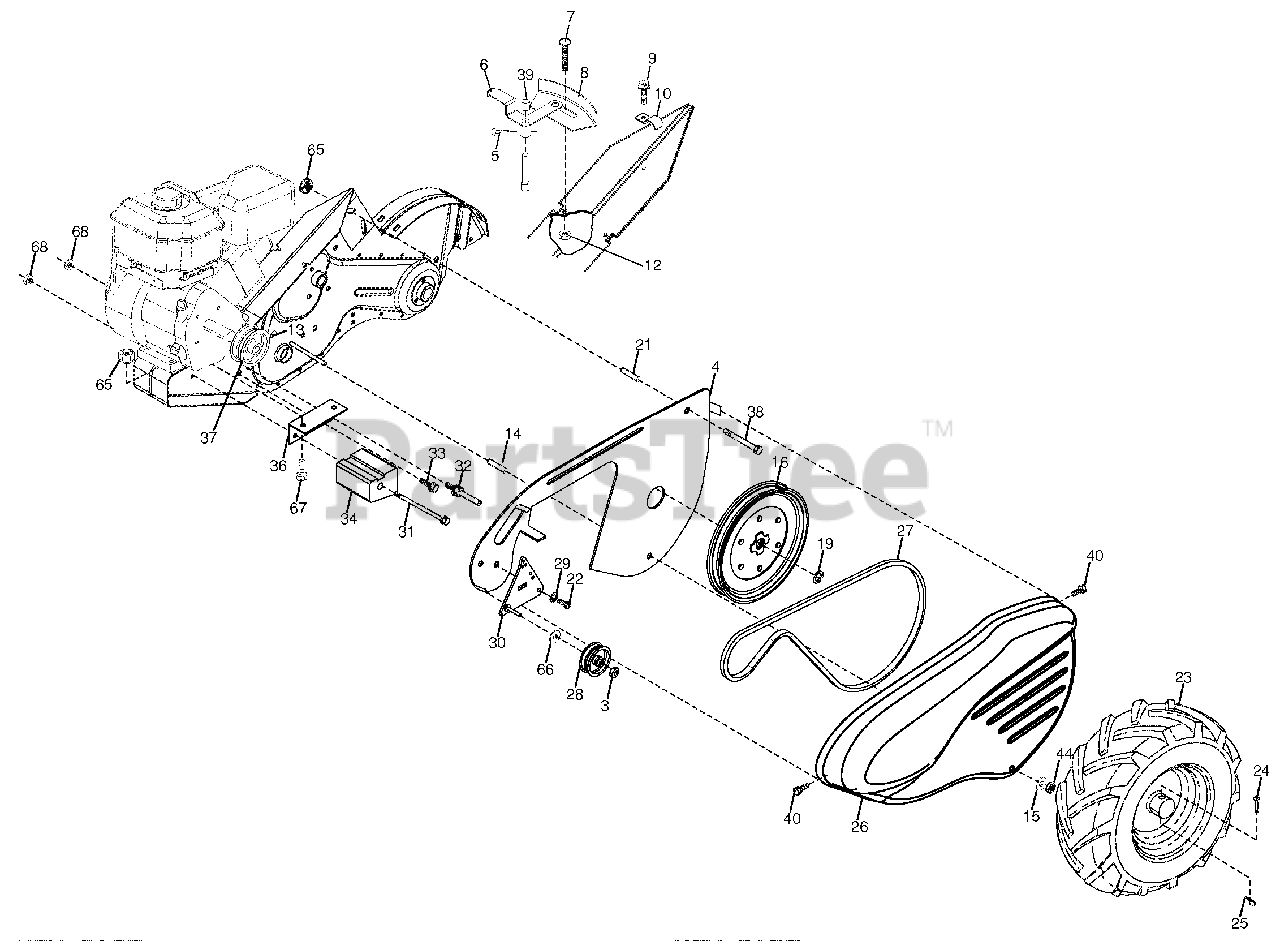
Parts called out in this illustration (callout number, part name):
3	Nut, Hex 3/8-16
4	Shield, Inner Belt Guard
5	Pin, Shift Lever
6	Lever, Shift
7	Bolt 1/4-20 unc x 1/2 Gr. 5
8	Plate, Shift Indicator
9	Screw, Tap Hex Head
10	Clip, Cable
12	Nut, Keps Hex 1/4-20 unc
13	Screw Set 5/16-18 x 3/8 Patch
14	Spacer, Split .327 x .42 x 2.0
15	Washer 11/32 x 11/16 x 16 Ga.
16	Sheave, Transmission
19	Ring, Retainer
21	Spacer, Split .327 x .42 x 1.2
22	Bolt, Hex Head 5/16-24 unf x 1
24	Rivet, Drilled
25	Retainer Spring
26	Guard, Belt
27	Belt, V
28	Pulley, Idler
29	Ring, Klip
30	Bracket, Idler
31	Bolt, Hex 5/16-16 x 12
32	Shaft, Idler Arm
33	Bolt, Hex 3/8-16 x 1
34	Counterweight, LH
36	Bracket, Reinforcement, LH
37	Sheave, Engine
38	Bolt, Fin Hex 5/16-18 x 2-3/4
39	Cap, Plunger
40	Screw Hex Wsh Hd #8-18 x 1/2
44	Locknut, Washer Insert 5/16-18
65	Nut, Hex, Flangelock
66	Washer 13/32 x 13/16 x 12 Ga.
67	Bolt, Hex Head, Gr. 25/16-18 x
68	Nut Keps Hex 3/8-16 unc
